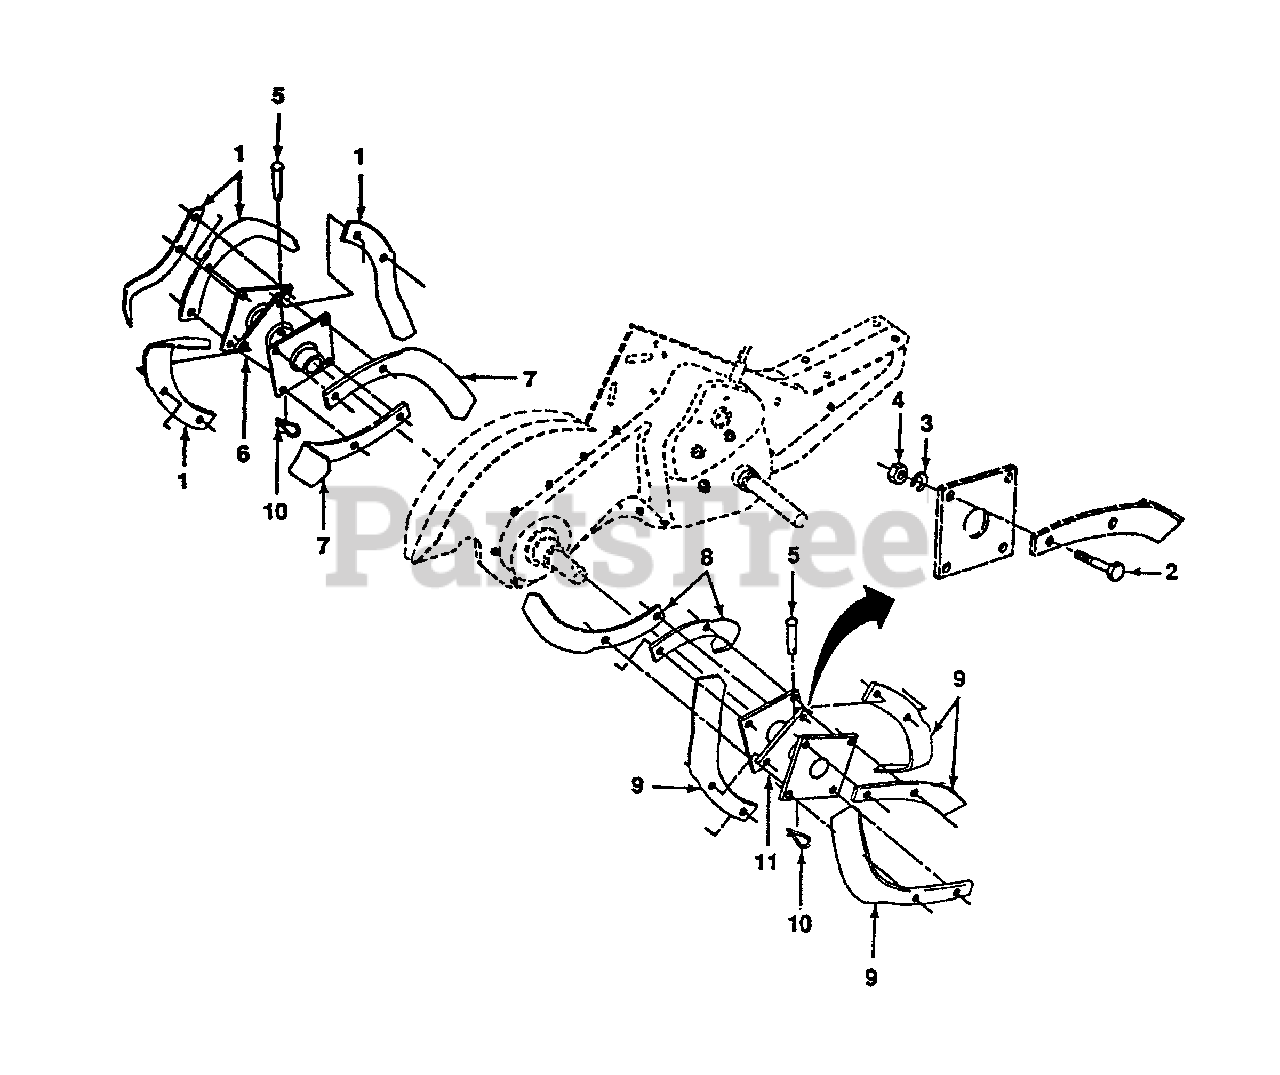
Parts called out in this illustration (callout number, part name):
1	Tine, L. H. Outer
2	Bolt, Hex 3/8-24 x 1
3	Washer, Lock 3/8
4	Nut, Hex 3/8-24
5	Clevis Pin
6	Assembly, Hub and Plate, L. H.
7	Tine, L. H. Inner
8	Tine, R. H. Inner
9	Tine, R. H. Outer
10	Clip, Hairpin
11	Assembly, Hub and Plate, R. H.
